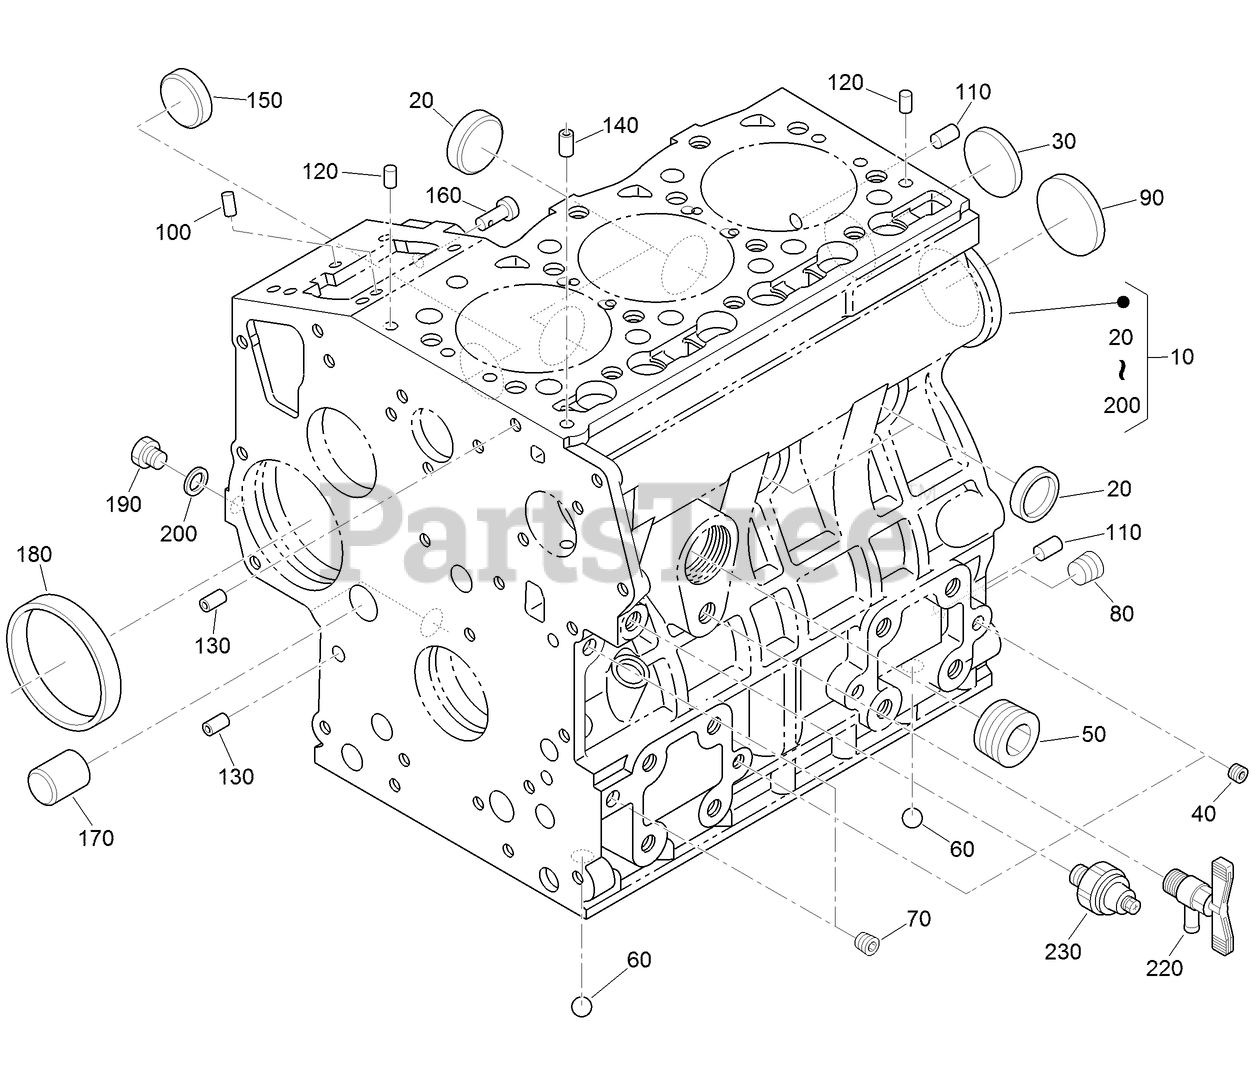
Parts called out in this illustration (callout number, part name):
10	CRANKCASE ASM
20	CAP-SEALING
30	CAP-SEALING
90	PLUG-EXPANSION
100	PIN-STRAIGHT
110	PIN-STRAIGHT
120	PIN-STRAIGHT
130	PIN-PIPE
140	PIN-PIPE
160	PIN-SPRING, START
180	BUSHING-GOVERNOR, GEAR
200	GASKET
220	DRAINCOCK ASM
230	SWITCH-OIL
